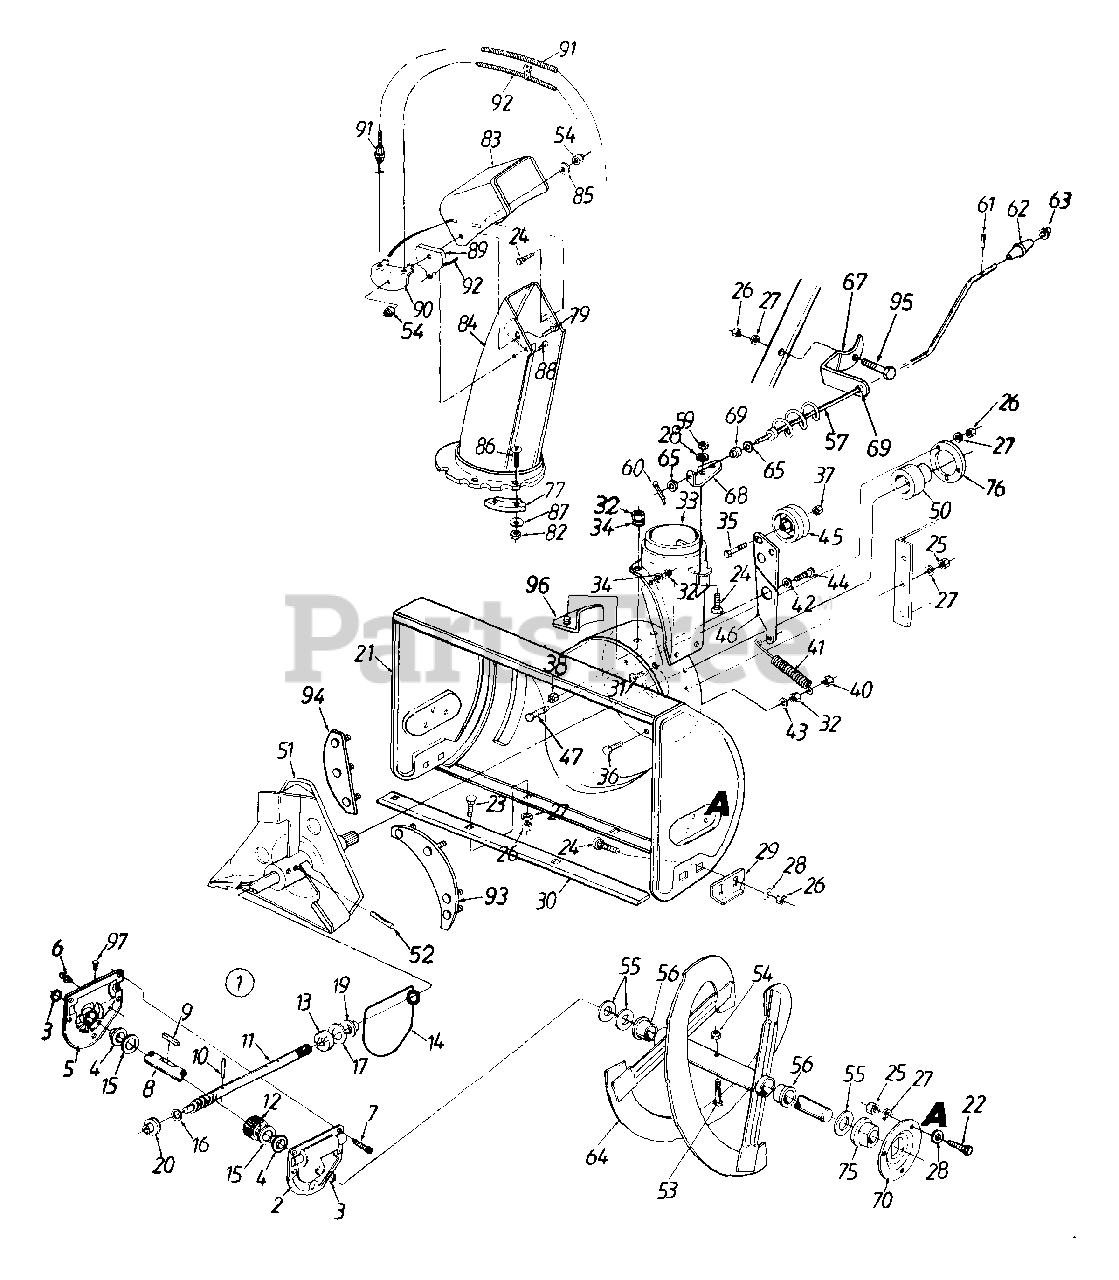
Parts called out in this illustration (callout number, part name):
1	Worm Drive Ass'y. Comp.
2	Reducer Housing - L.H.
4	Flange Bearing .75" I.D.
5	Reducer Housing - R.H.
6	Grease Fitting
7	Hex TT-Tap Scr. 1/4-20 x .75" Lg.
8	26" Auger Shaft
9	#61 Hi-Pro Key 3/16" x 5/8" Dia.
10	Spiral Pin 1.25" Lg.
11	Impeller Shaft
12	Worm Gear
13	Thrust Collar
14	"O"-Ring (Special)
15	Fl-Wash. .76" I.D. x 1.5" O.D.
16	Fl-Wash. .5" I.D. x 1" O.D.
17	Fl-Wash. .76" I.D. x 1.49" O.D.
19	Flange Bearing .75" I.D.
20	Flange Bearing .503" I.D.
21	26" Auger Housing Ass'y.
22	Hex Bolt 5/16-24 x .75" Lg.
23	Carriage Bolt 5/16-18 x .62" Lg.
24	Carriage Bolt 5/16-18 x .75" Lg.
25	Hex Nut 5/16-24 Thd.
26	Hex Nut 5/16-18 Thd.
27	L-Wash. 5/16" I.D.
28	Bell-Wash. .345" I.D. x .88" O.D.
30	26" Shave Plate
31	Truss Mach. Scr. 1/4-20 x .5" Lg.
32	Hex Nut 1/4-20 Thd.
33	Chute Adapter
34	Spring Washer 1/4" I.D.
35	Hex Bolt 3/8-24 x 1.5" Lg. (Gr. 5)
36	Hex Bolt 1/4-20 x .75" Lg. (Gr. 5)
37	Hex Ins. L-Nut 3/8-24 Thd.
38	Hex Top L-Nut 3/8-16 Thd.
40	Hex L-Nut 1/4-20 Thd.
41	Ext. Spring 3.6" Lg.
42	Fl-Wash. 5/8" I.D. x 1.25"
43	L-Wash. 1/4" I.D.
44	Shld. Bolt .625" Dia. x .170" Lg.
45	Fl-Idler 2.75" O.D.
47	Hex Bolt 5/16-18 x 5/8" Lg.
50	Ball Bearing .75" I.D.
52	Spiral Pin 1.5" Lg.
53	Shear Bolt 5/16-18 x 1.5" Lg.
54	Hex Cent. L-Nut 5/16-18 Thd.
55	Fl-Wash. .76" I.D. x 1.49"
56	Flange Bushing .8" I.D.
57	Chute Crank Ass'y.
59	Hex Ins. L-Nut 5/16-18 Thd.
60	Cotter Pin 3/32" Dia. x .75"
61	Roll Pin 1/8" Dia. x .63" Lg.
62	Chute Crank Knob
64	Spiral Ass'y. - L.H.
65	Fl-Wash. .385" I.D. x .62" O.D.
69	Plastic Bushing .38" I.D.
75	Plastic Bearing w/Flats
76	Bearing Housing
77	Chute Flange Keeper
79	Carriage Bolt 5/16-18 x 1.5" Lg.
82	Hex L-Nut 1/4-20 Thd.
83	Upper Chute
84	Lower Chute
85	Fl-Wash. .344" I.D. x 1.125"
86	Truss Mach. Scr. 1/4-20 x .75" Lg.
87	Fl-Wash. 1/4" I.D.
88	Hex AB-Tap Scr. 1/4 x .62" Lg.
89	Cable Guide
91	Chute Control Cable
92	Chute Control Cable w/Clip
96	Chute Reinforcement
